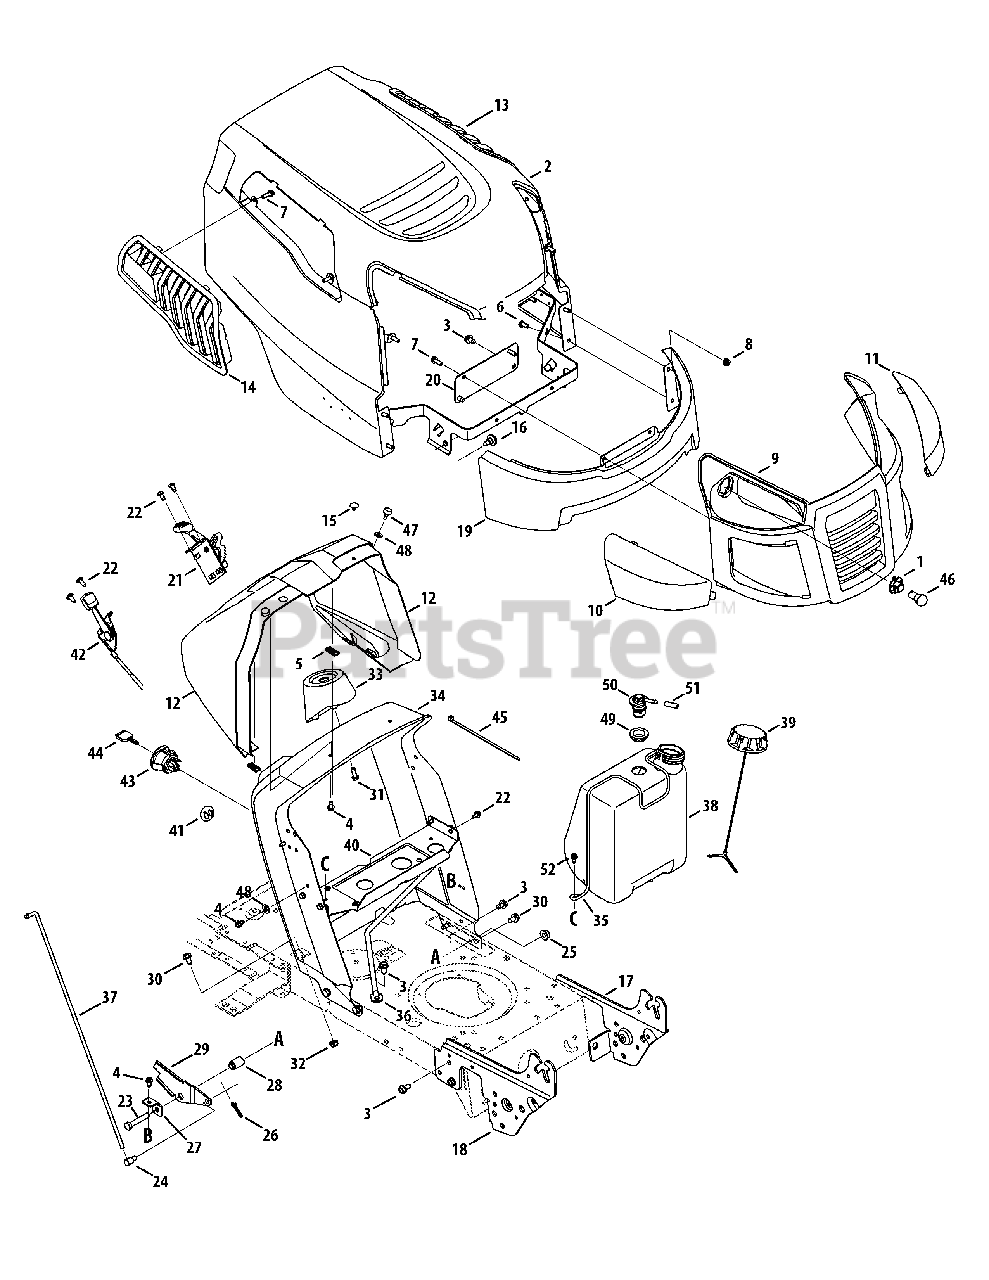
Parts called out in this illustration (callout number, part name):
1	Bulb Socket
2	Hood Assembly
3	Screw, 5/16-18 x .750
4	Hex Washer Screw, 1/4-20 x .500
5	Tin Clip Nut, 1/4-20
6	Hex Screw, 1/4-20 x .620
7	Screw, 1/4 x .750
8	Nut, Hex Flange Insert Lock, 1/4-20
10	Headlight Lens, RH
11	Headlight Lens, LH
12	Dash Collar
13	Hood Scoop, LH
14	Hood Scoop, RH
15	Bumper
16	Shoulder Screw, 5/16-18
17	Left Support Pivot Bracket
18	Right Support Pivot Bracket
19	Lower Grill
20	Lower Grill Bracket
21	Speed Selector, 7-Speed
22	Self-Tap Screw, 1/4-20
23	Hex Head Screw, 3/8-16
24	Ferrule, 1/4-20 x 1.00
25	Nut, Hex Flange Insert Lock, 3/8-16
26	Cotter Pin
27	Speed Latch Support Tab
28	Flange Spacer
30	Self-Tap Screw, 5/16-18
31	Hex Screw, 1/4 x .750
32	Nut, Hex Flange Lock, 5/16-18
33	Steering Support
35	Fuel Tank Support Rod
36	Dash support Rod
37	Speed Selector Control Rod
38	1.36 Gallon Fuel Tank
39	Fuel Cap
40	Gas Tank Support Bracket
41	Choke Plug
42	Throttle/Choke Assembly
43	Key Switch Module
44	Key (2 pack)
45	Cable Tie
46	Headlight Bulb
47	Ratchet Clip: .250 x .500
48	Flat Washer, .25 x .630 x .0515
49	Rubber Grommet
50	Fuel Rollover Valve
51	Vent Hose
52	Hex Washer Screw, 1/4-20 x .625
